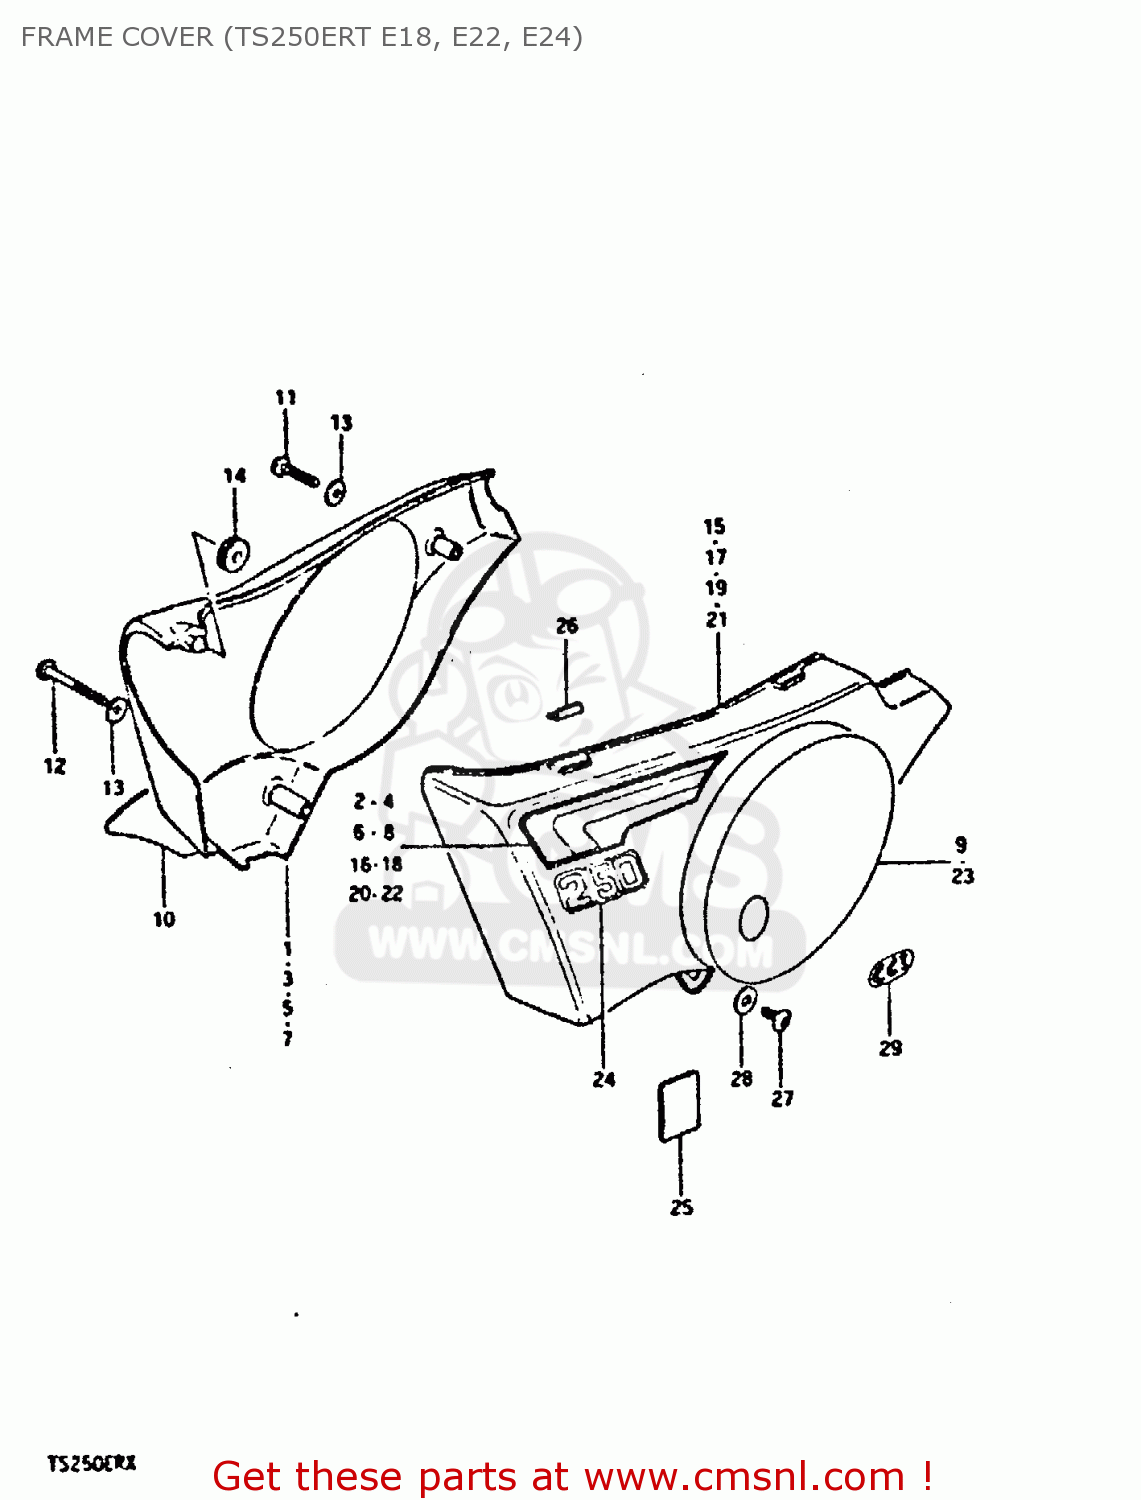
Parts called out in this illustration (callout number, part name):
1	COVER, FRAME RH (BLUE)
2	TAPE, RH
3	COVER, FRAME RH (RED)
4	TAPE, RH
5	COVER, FRAME RH (YELLOW)
6	TAPE, RH
7	COVER, FRAME RH (WHITE)
8	TAPE, RH
9	EMBLEM, RH
10	EMBLEM,FRAME COVER,RIGHT
11	SCREW
12	SCREW
13	WASHER
14	CUSHION
15	COVER, FRAME LH (BLUE)
16	TAPE, LH
17	COVER, FRAME LH (RED)
18	TAPE, LH
19	COVER, FRAME LH (YELLOW)
20	TAPE, LH
21	COVER, FRAME LH
22	TAPE, LH
23	EMBLEM, LH
24	EMBLEM, "250"
25	CUSHION,FRAME COVER
26	PROTECTOR(170X95X3.0)
27	SCREW 6X12
28	WASHER
29	EMBLEM,CCIS
